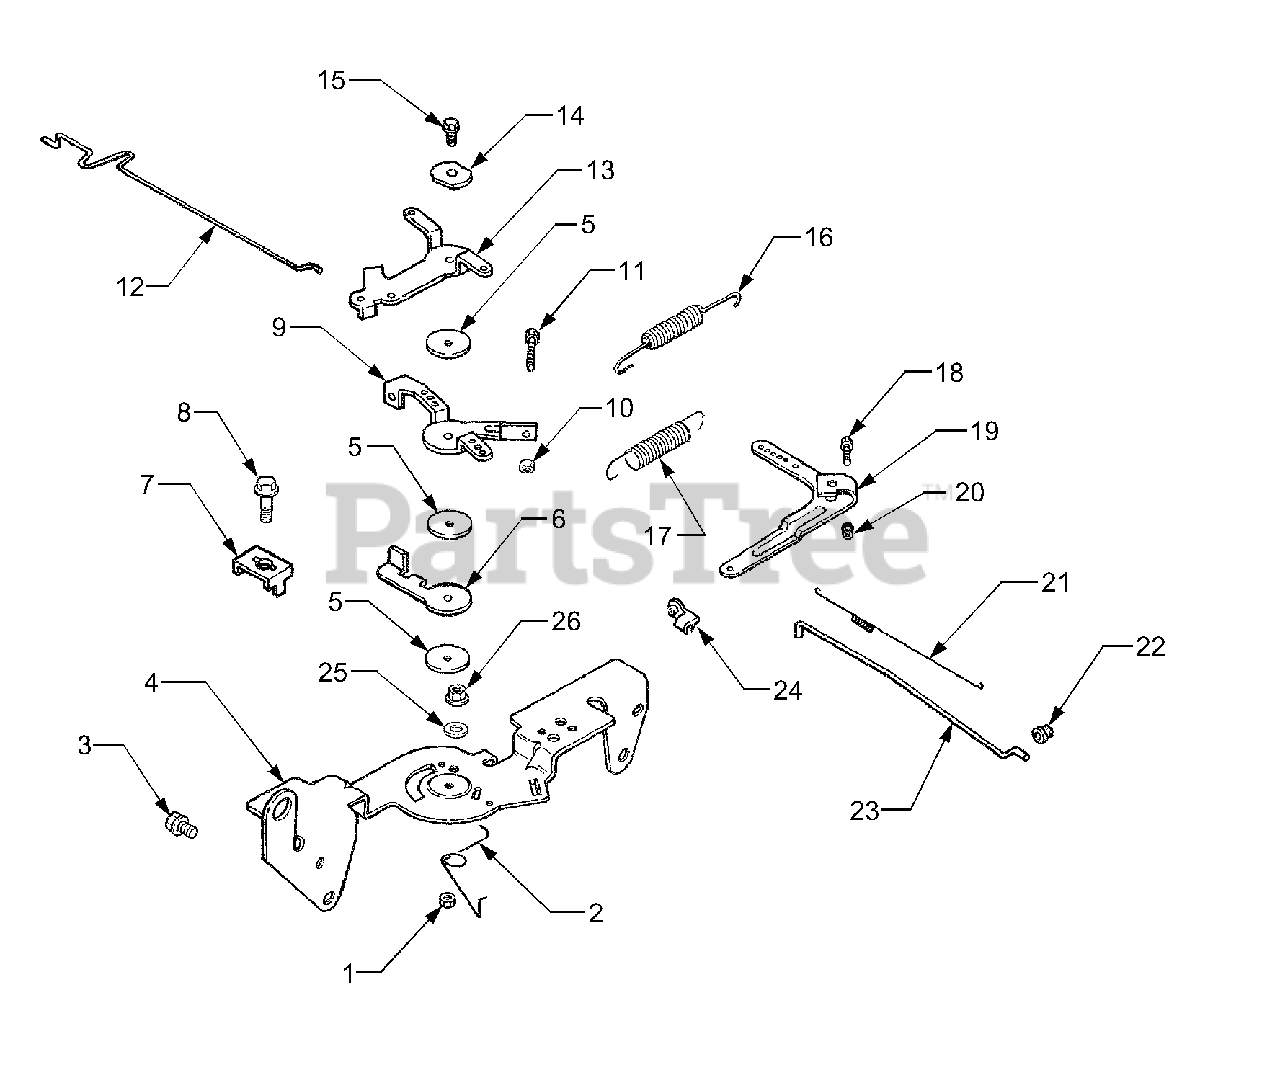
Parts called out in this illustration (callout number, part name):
1	Nut, Hex Lock M5 x 0.8
2	Spring, Choke Return
3	Screw, Hex Flange M6 x 1.0 x 16
4	Bracket, Control
5	Washer , Plain 5.5mm
6	Lever, Throttle Actuator
7	Clamp, Cable
8	Screw, Hex Flange M5 x 0.8 x 16
9	Lever, Throttle Control
10	Nut, Hex M4 x 0.7
11	Screw, Hex Cap M4 x 0.7 x 30
12	Linkage, Choke
13	Lever, Choke
14	Washer, Spring 1/4"
15	Screw, Hex Flange M5 x 0.8 x 20
16	Spring, Throttle Limiter
17	Spring, Governor
18	Screw, Round Hd. Square Neck
19	Lever, Governor
20	Nut, Hex Flange M6 x 1.0
21	Spring, Linkage
22	Bushing, Linkage Retaining
23	Linkage, Throttle
24	Bushing, Linkage Retaining
